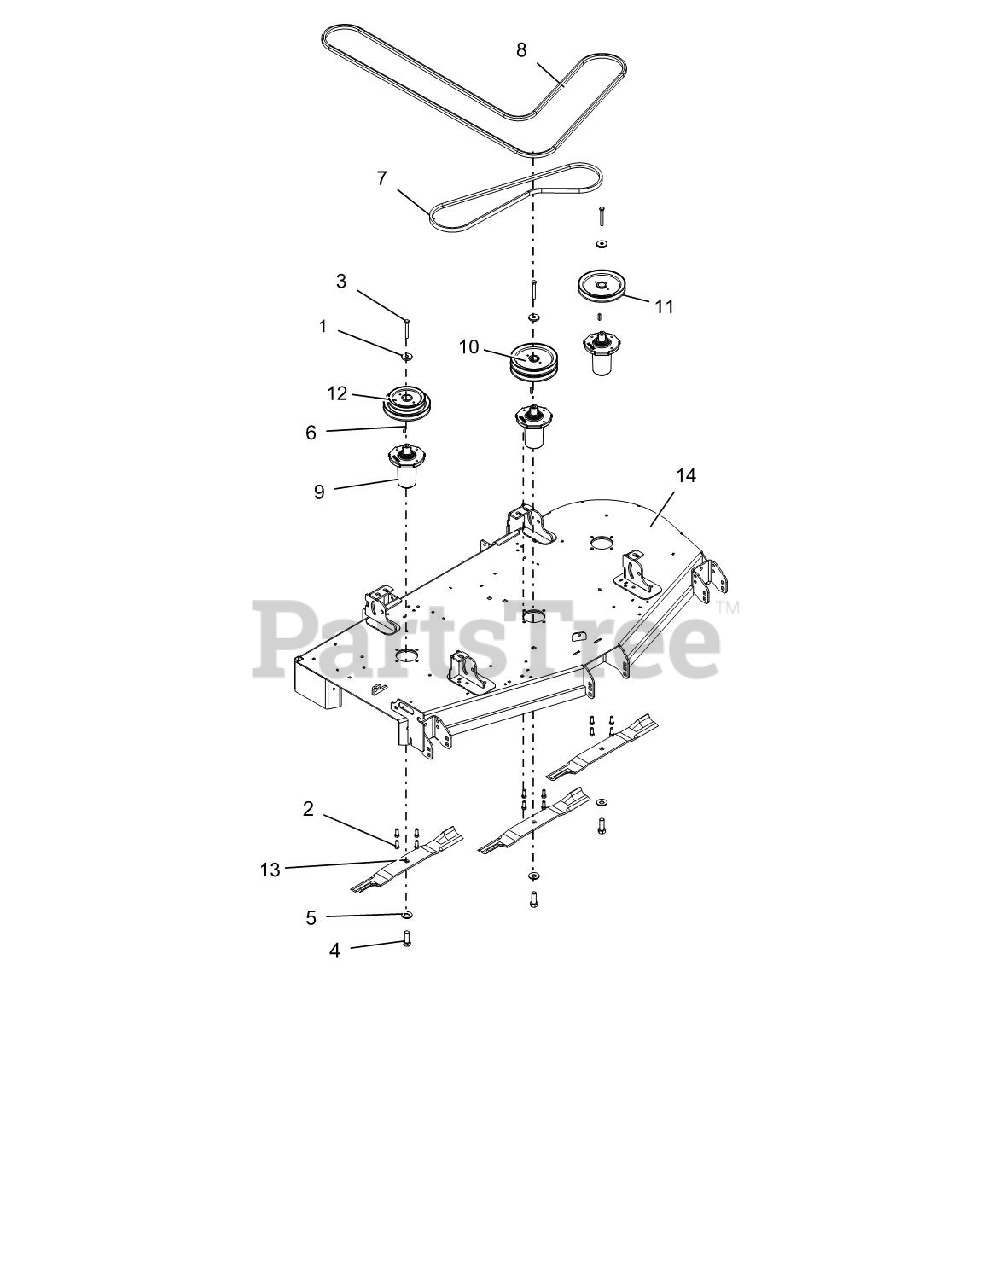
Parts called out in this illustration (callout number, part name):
1	RETAINER, SHEAVE SPINDLE
2	BLT-HEX .38-16X1.00 GR5 YWZC EP30
3	BLT-HEX .38-16X2.75 GR8 YWZC
4	BLT-HEX .625-18X1.75 GR8 YWZC
5	WSHR, BLVL-.63X1.625X.14
6	KEY-SQ .250X.250X1.00 RC 40-50
7	V-BELT, B-COGGED
8	BELT, BB 118.00 WRAPPED HEX
9	SERVICE, ASM SPINDLE- DUCTILE
10	PULLEY, DOUBLE 1.000 ID X 6.750 OD-BLACK
11	PULLEY, V-1.00 ID X 6.75 OD
12	PULLEY, DOUBLE -1" ID X 6.75" & 5.25" OD
13	BLADE, MOWER (20.50")
14	WLDMT, 60" SIDE DISCH DECK
